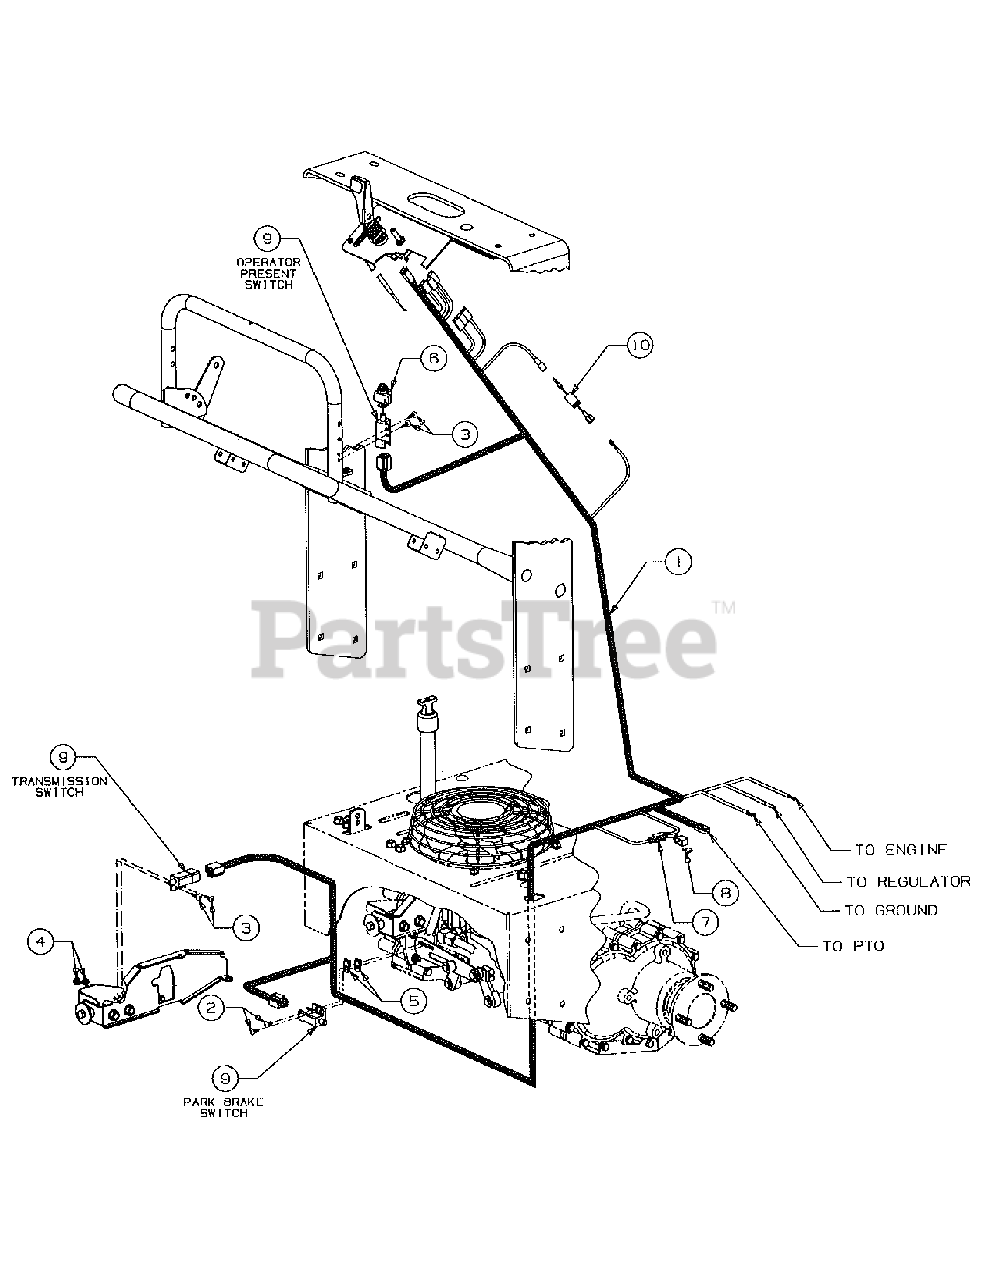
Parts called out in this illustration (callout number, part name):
2	Screw, Truss Mach #10-24 x .50
3	Screw, Pan Hd Cutting, #10-24 x .75
4	Nut, Hex Lock, #10-24
5	Nut, Speed
6	Cover, Protective
7	Holder, Inline Fuse
8	Fuse, 20 Amp Mini
9	Switch, Doulbe Poled Plunger
10	Capacitor, Clutch
